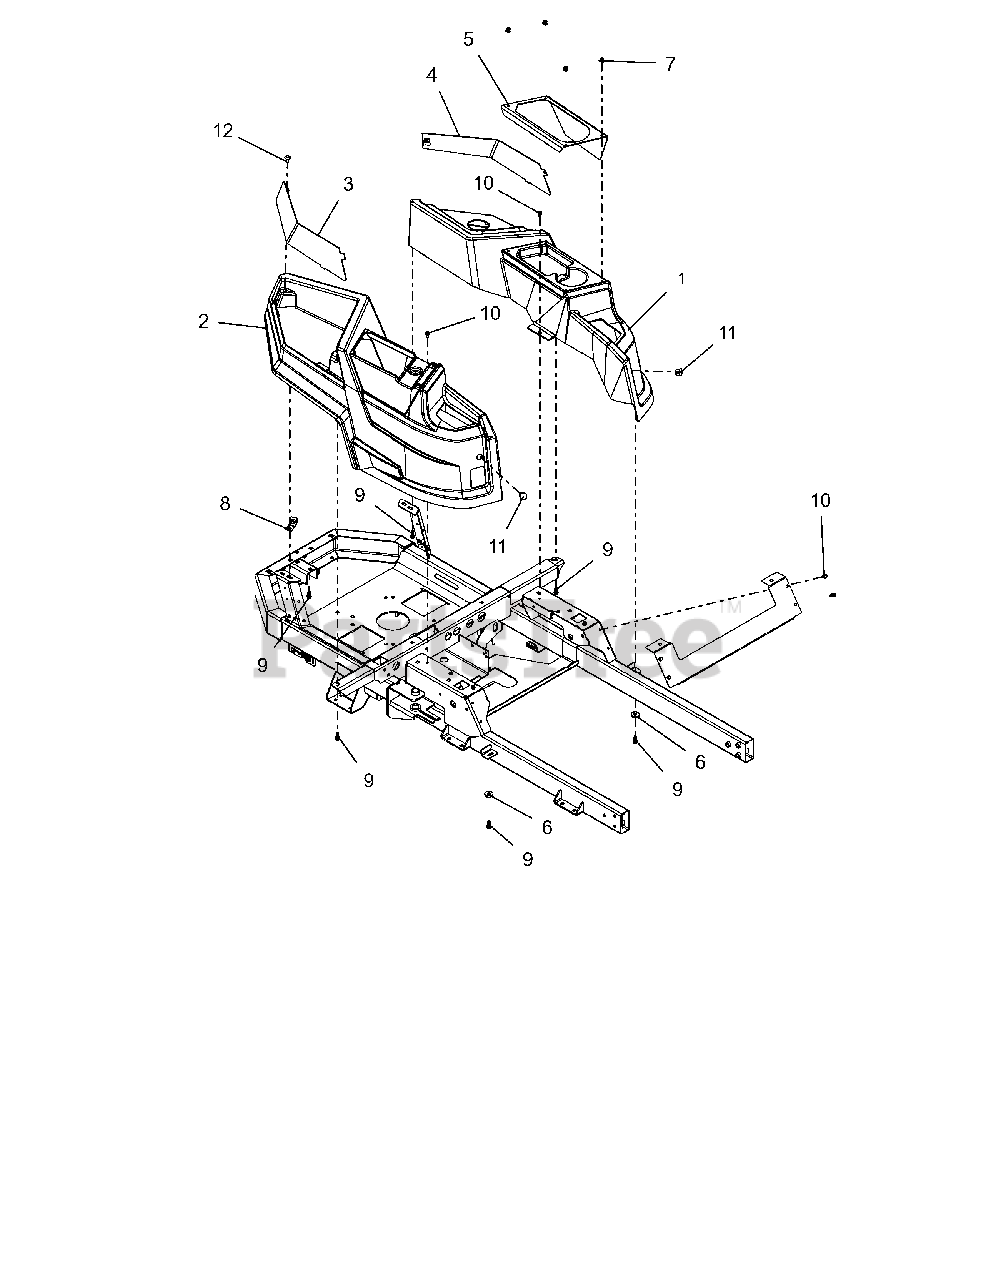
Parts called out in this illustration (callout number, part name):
1	FENDER, LH -ZOOM
2	FENDER, RH -ZOOM
3	WLMT, FENDER BLOCKOFF-RH
4	WLMT, FENDER BLOCKOFF-LH
5	PANEL, CUPHOLDER/STORAGE (LH)
6	WSHR, FLT .406X1.00X.188 ZCC
7	RIVET, PLASTIC .195 DIA.
9	SCR-.312X.75 #14H H/W/H H/L CZ
10	SCR-TAP .25-20X.50 HWH ZCC
11	PLUG, HOLE .75 (BLACK)
12	XMAS TREE FASTNER-BLACK
